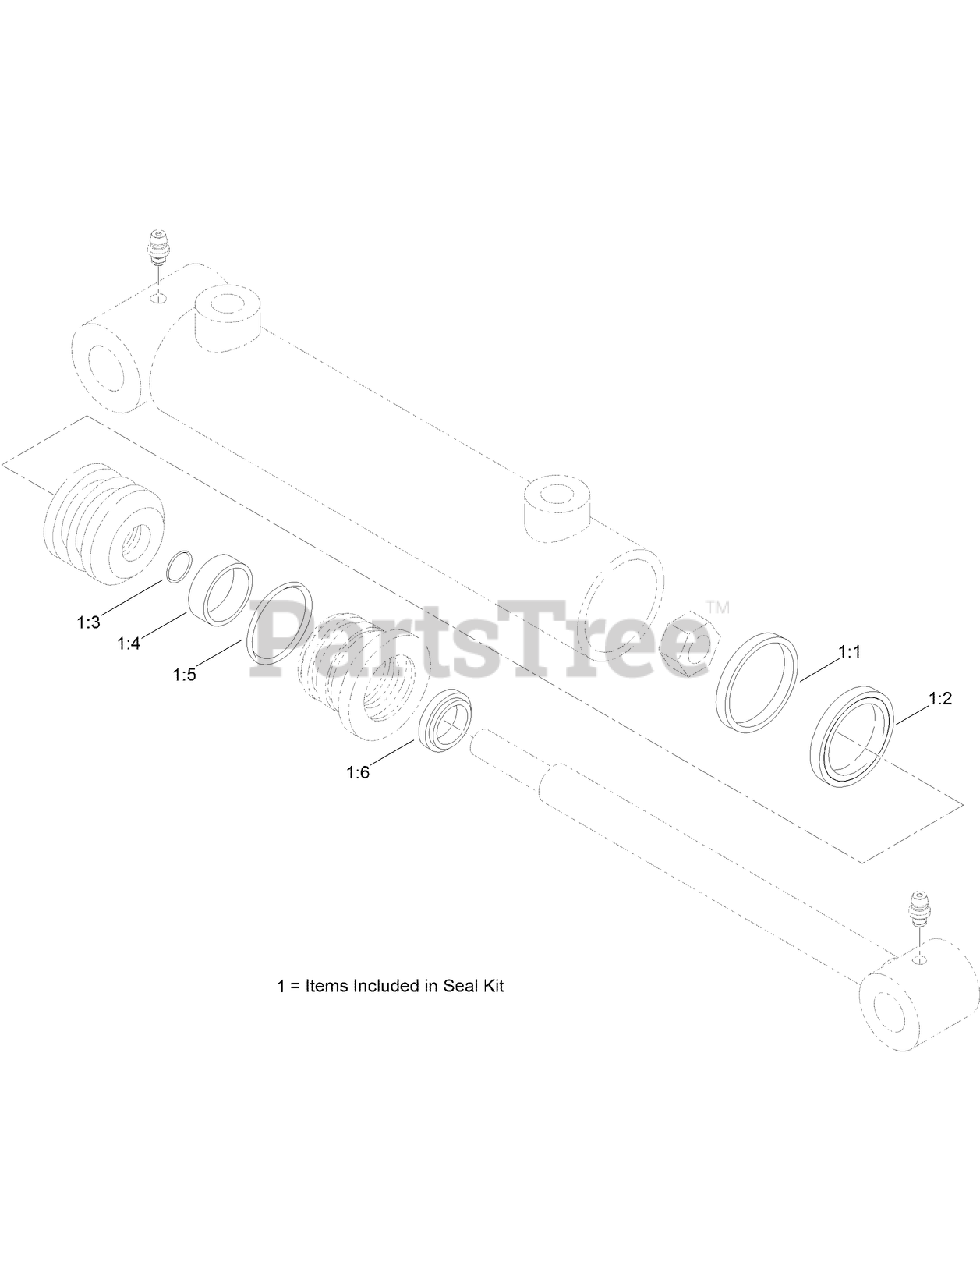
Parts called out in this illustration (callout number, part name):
1:1	RING-WEAR
1:2	Seal-Psp
1:3	O-RING
1:4	O-RING
1:5	Seal-Polypak
1:6	Wiper-Rod
